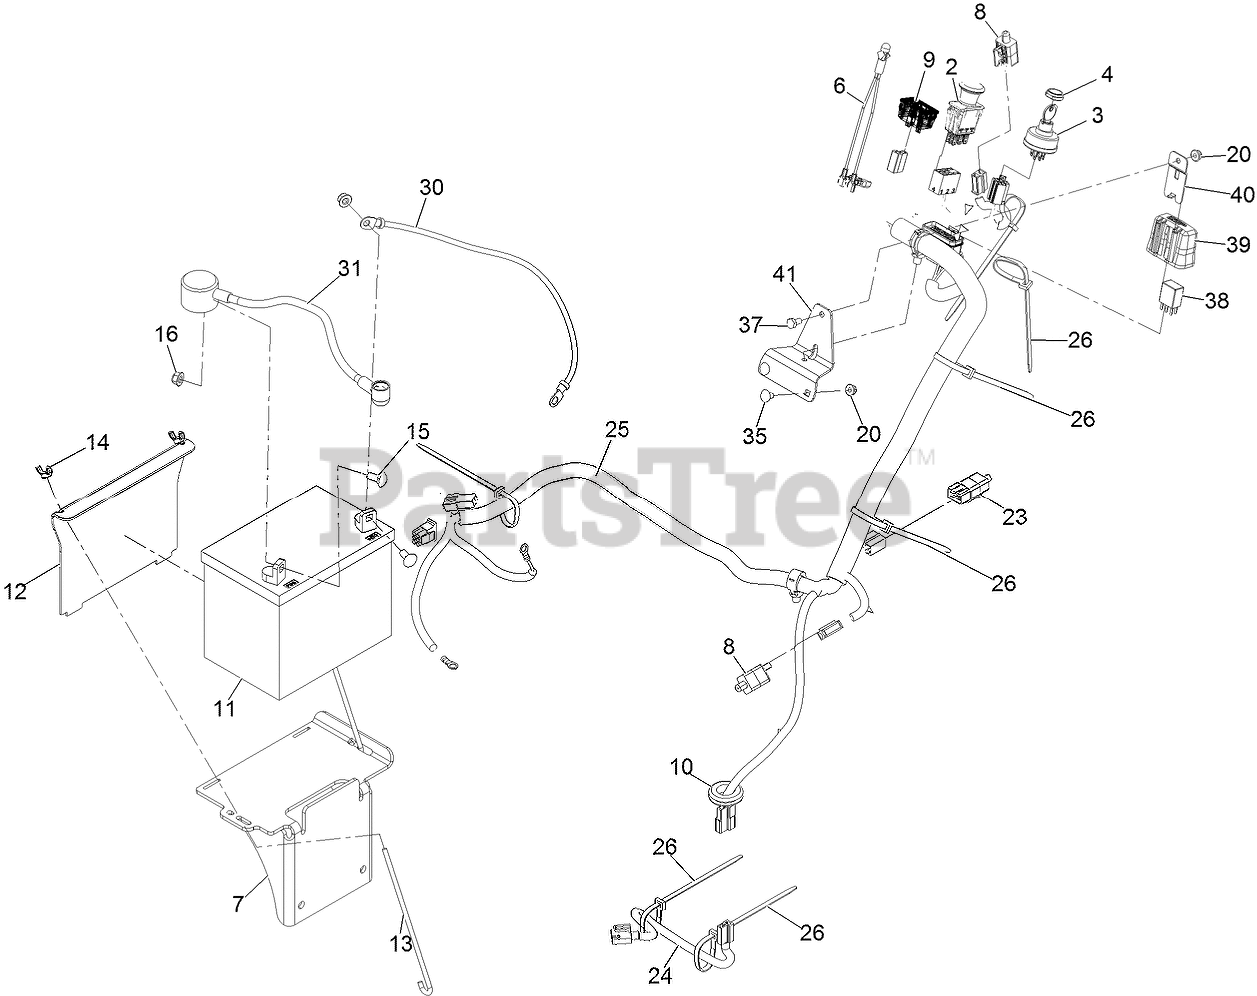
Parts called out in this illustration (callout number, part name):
2	SWITCH-PTO
3	SWITCH, KEY START
4	NUT-SWITCH, IGNITION
6	INDICATOR-LED, RED
7	WELD, BATTERY MOUNT
9	METER-HOUR
10	GROMMET
11	Battery
12	BRACKET, BATTERY HOLD DOW
13	BOLT-HOLDDOWN
14	WINGNUT
15	BOLT-CARR
16	NUT-HF, NI
23	SWITCH, 2 POLE
24	HARNESS-CLUTCH PIGTAIL
25	HARNESS-WIRING
26	TIE-PLASTIC
31	ASM,POSITIVE BATTERY CABL
35	SCREW-CARR
37	SCREW-HH
38	RELAY-MICRO 280, SPDT
39	COVER-BLOCK, FUSE
40	CLIP-MOUNTING
41	BRACKET-MOUNTING, FUSEBLO
